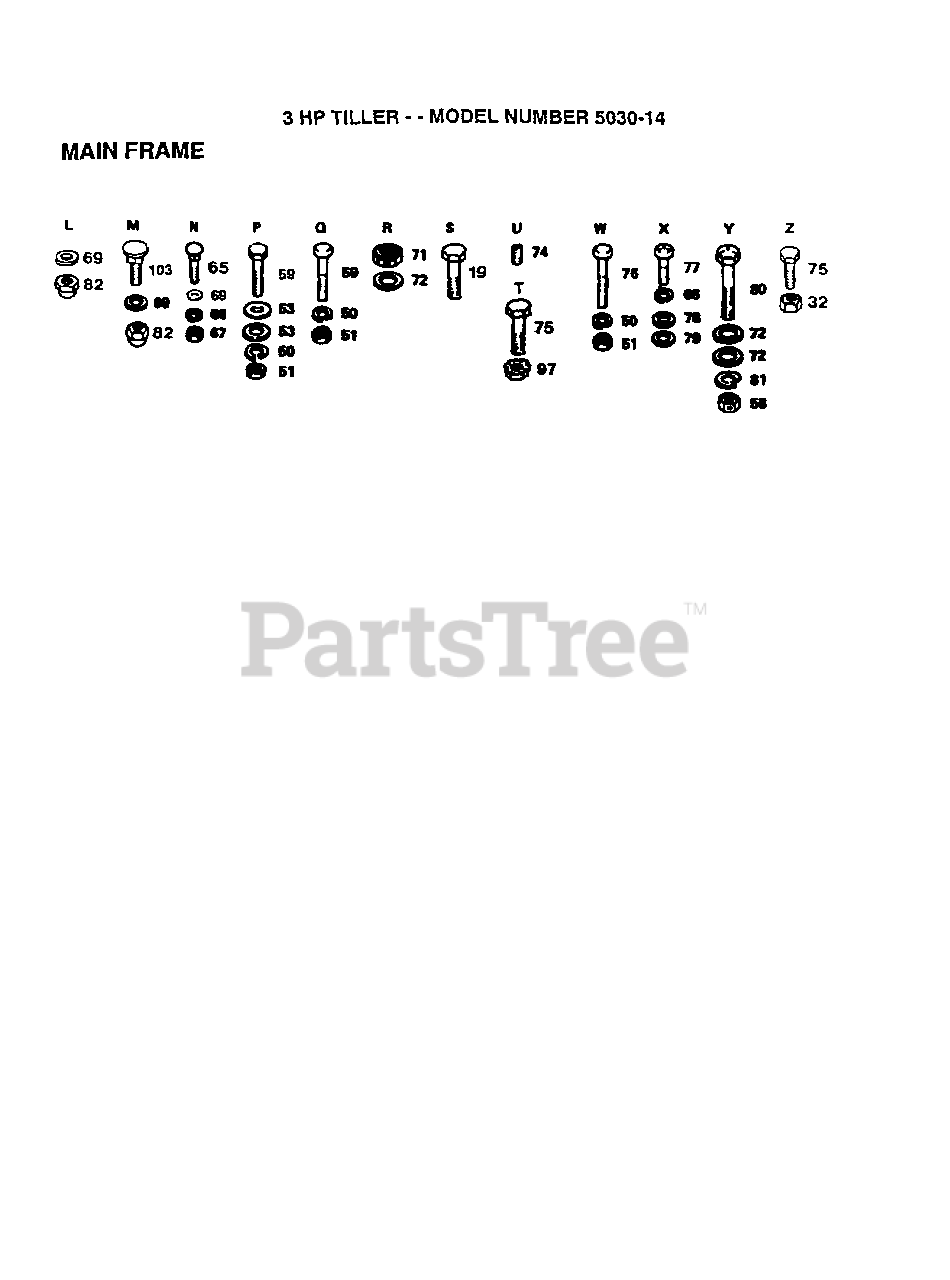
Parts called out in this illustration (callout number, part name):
50	LOCKWASHER
51	NUT.HEX.5/16-18
53	WASHER
58	GRIPCO NUT
65	BOLT T
66	LOCKWASHER
69	WASHER
72	WASHER
74	SET SCREW
75	BOLT.HEX.5/16-1.5
77	BOLT
78	WASHER
79	WASHER
80	BOLT.3/8-24X3.75
81	LOCKWASHER
82	NUT-CAP TI
103	BOLT
